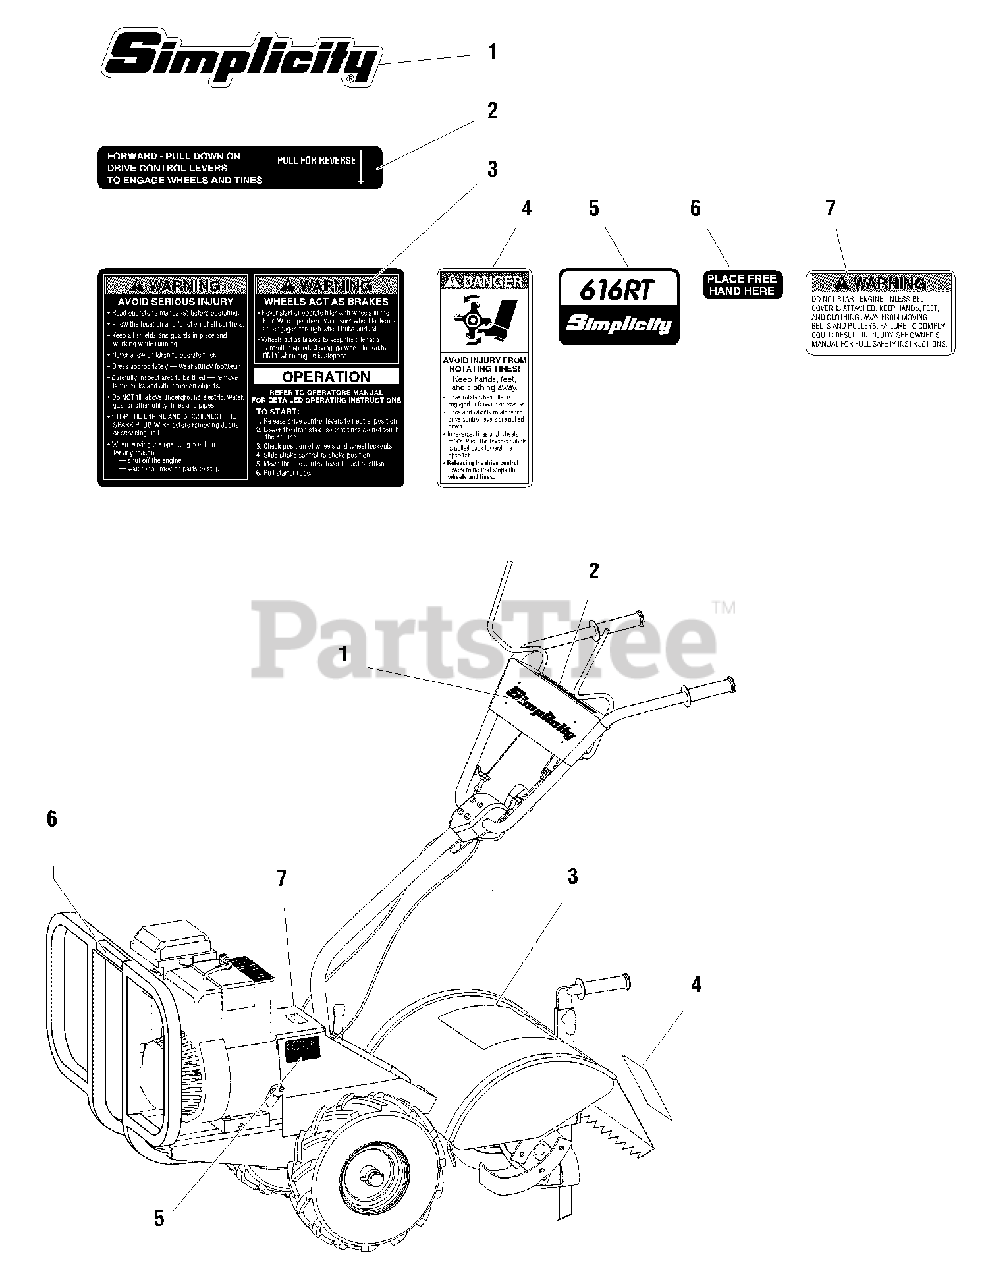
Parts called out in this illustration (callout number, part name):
1	DECAL, Simplicity
2	DECAL, Console Forward/Reverse Instructions
3	DECAL, Hood, Operator Instructions
4	DECAL, Tine Hood
5	DECAL, Belt Cover
6	DECAL, Brush Bar
7	DECAL, Warning, Blet Cover
